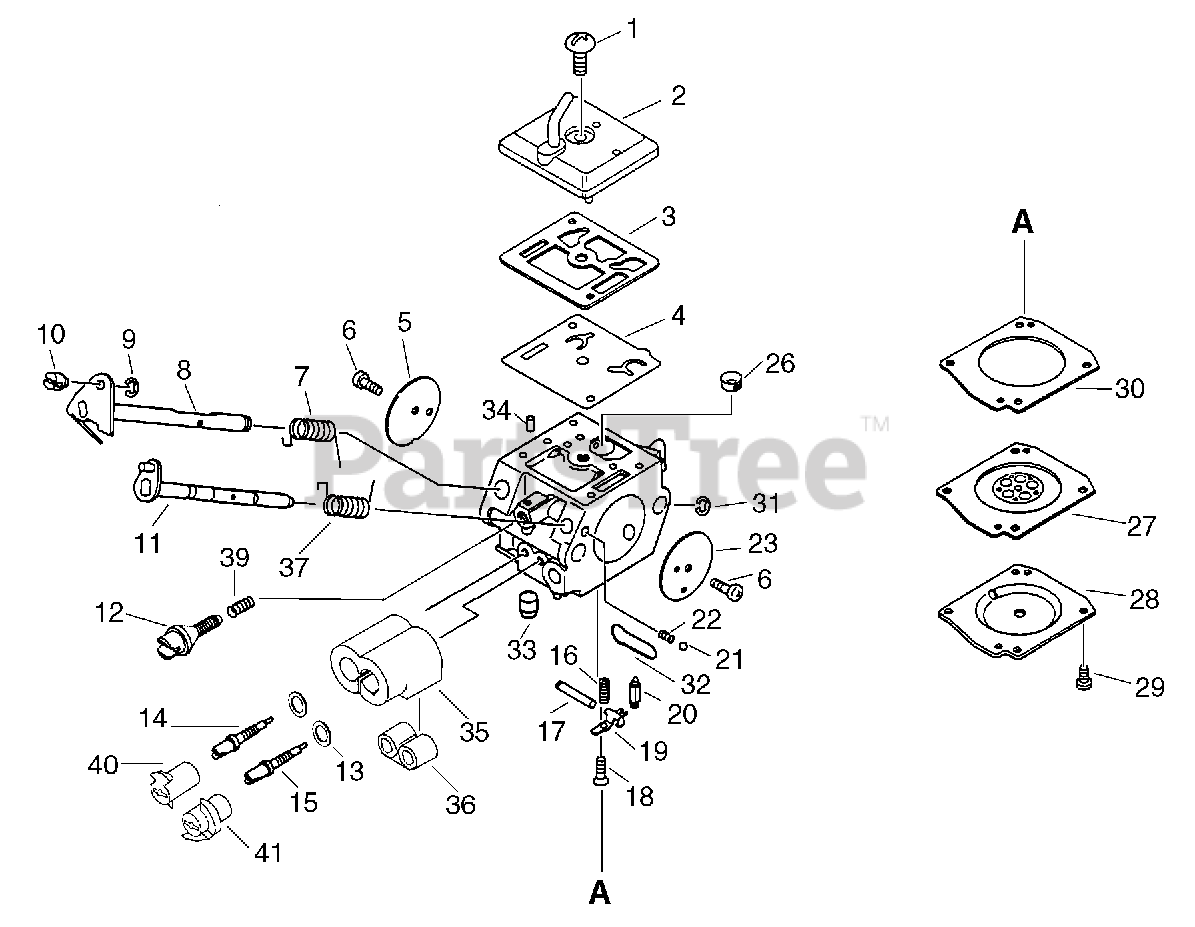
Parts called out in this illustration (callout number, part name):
1	SCREW, PUMP COVER
2	COVER, PUMP
3	GASKET, PUMP
4	DIAPHRAGM, PUMP
5	VALVE, THROTTLE
7	SPRING, RETURN
8	SHAFT, THROTTLE
9	RING, RETAINING
10	SWIVEL
11	SHAFT, CHOKE
12	SCREW, THROTTLE ADJUST
14	NEEDLE - LOW SPEED
15	NEEDLE - HIGH SPEED
17	PIN, METERING LEVER
18	SCREW, METERING LEVER PIN
19	LEVER, METERING
20	VALVE, INLET NEEDLE
21	BALL, CHOKE
22	SPRING
23	VALVE, CHOKE
26	STRAINER
27	DIAPHRAGM
28	COVER, DIAPHRAGM
30	GASKET, METERING
31	RING, RETAINING
32	PLUG, WELCH
33	NOZZLE, CHECK VALVE
34	PIECE, FRICTION
35	RETAINER, LIMITER CAP
36	SCREW, BOOT ADJUST
37	SPRING, CHOKE RETURN
39	SPRING, IDLE ADJUST
40	CAP, LIMITER
41	CAP, LIMITER
